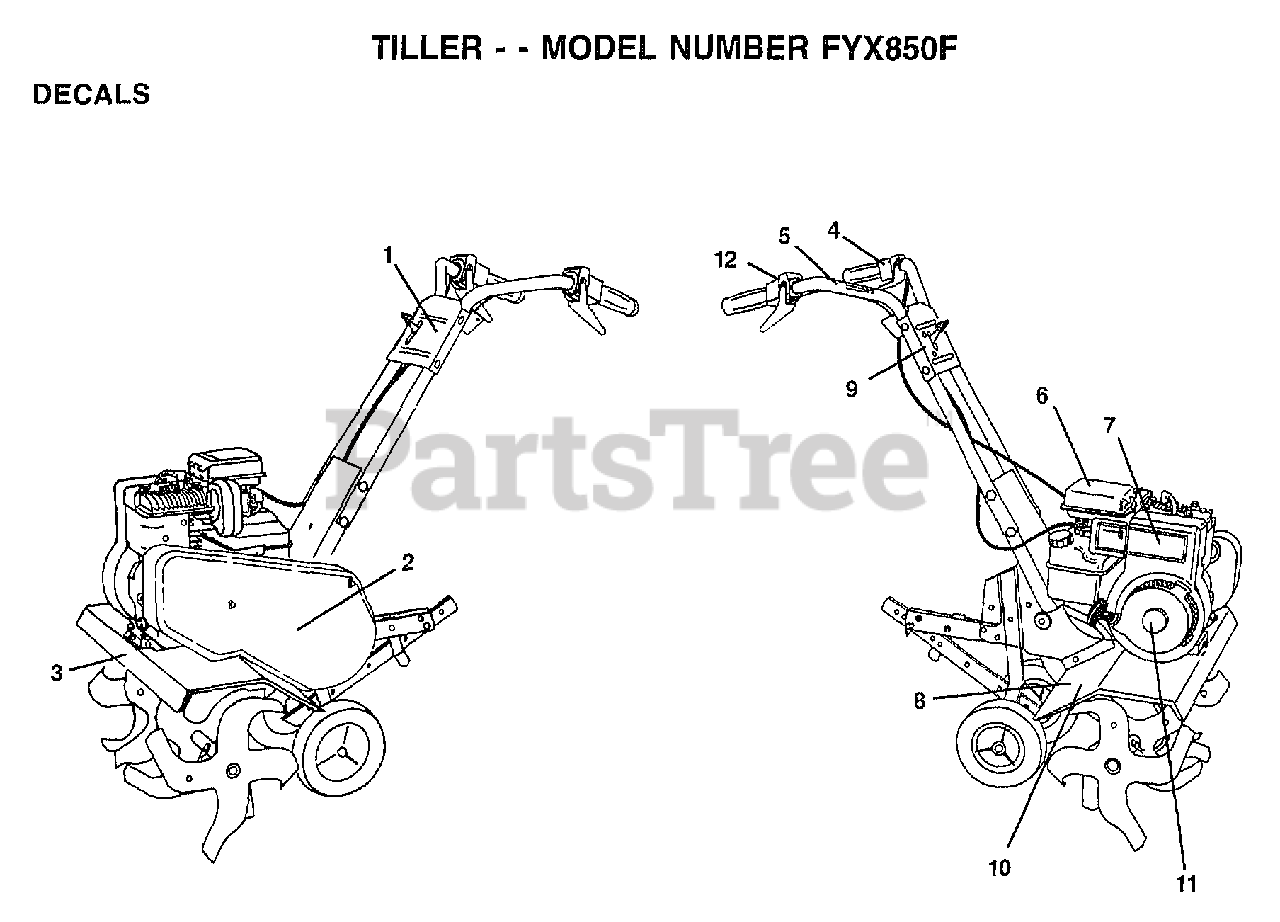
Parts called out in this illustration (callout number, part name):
1	DECAL HANDLE BRKT
2	DECAL.BELT.GUAR
3	DECAL TINE SHIELD
4	DECAL.CONTROL FOR
5	DECAL-PLACEMENT
6	DECAL TI
7	DECAL
8	DECAL-WARNING
9	"DECAL CONTROL,PNL"
10	DECAL.EURO.ST.CE.
12	DECAL.CONTROL.REV
